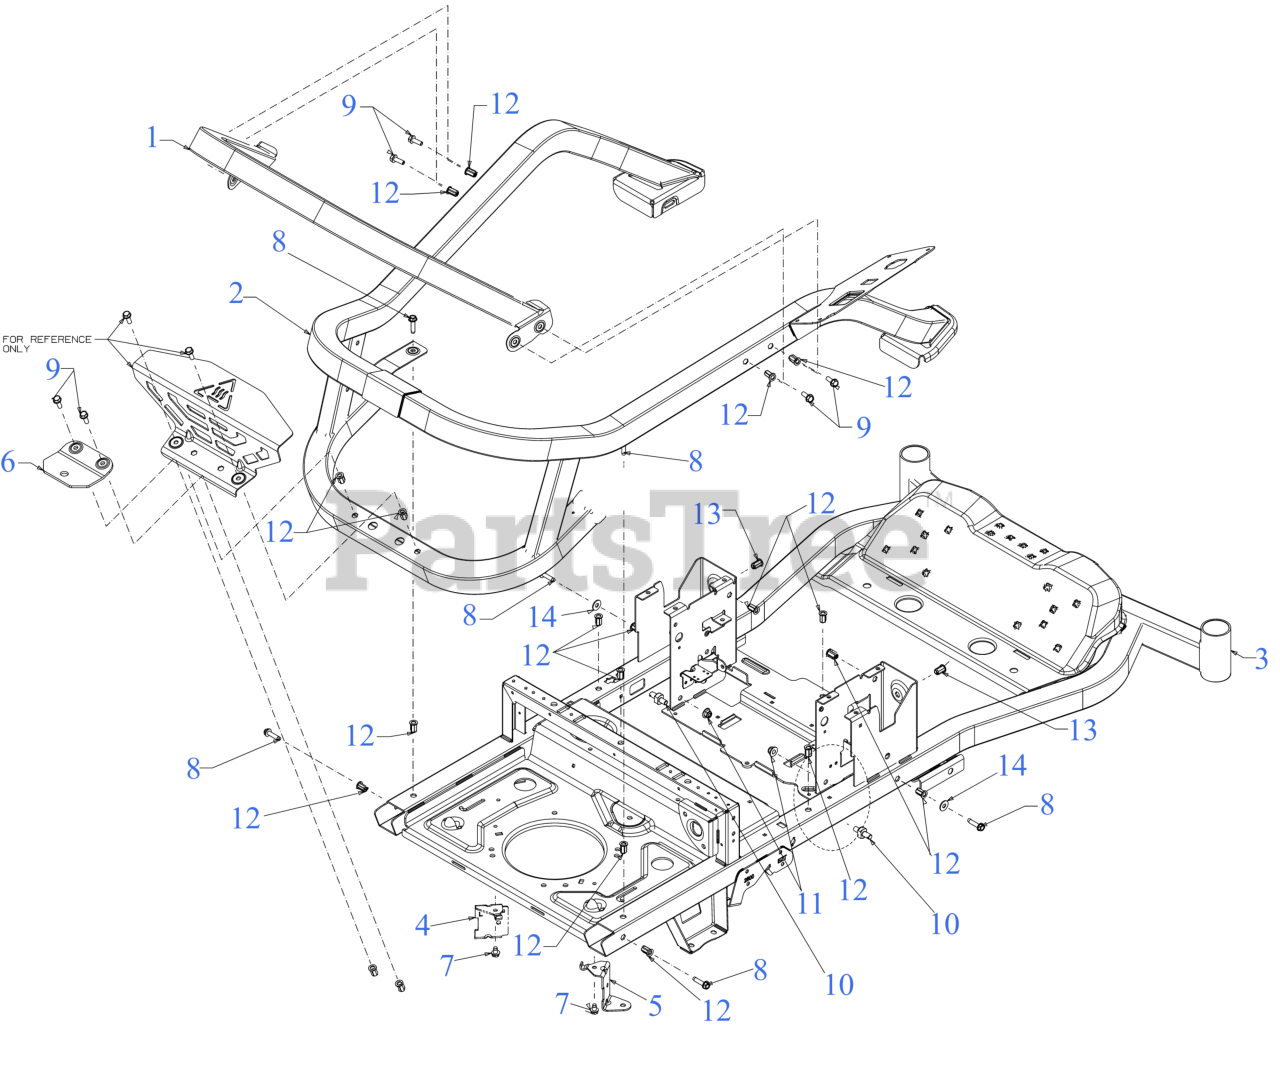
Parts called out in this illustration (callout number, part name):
1	UPPER FRAME HOOP
2	UPPER FRAME
3	FRAME
4	TRANSMISSON MOUNT SUPPORT (LH)
5	TRANSMISSON MOUNT SUPPORT (RH)
6	HITCH PLATE
7	SCREW 5/16-18 x .500
8	SCREW 5/16-18 x 1.25
9	SCREW 5/16-18 x .875 GR5
10	SHOULDER STUD
12	NUT RIVET 5/16-18
13	NUT RIVET 5/16-18 LOCK
14	FLAT WASHER
